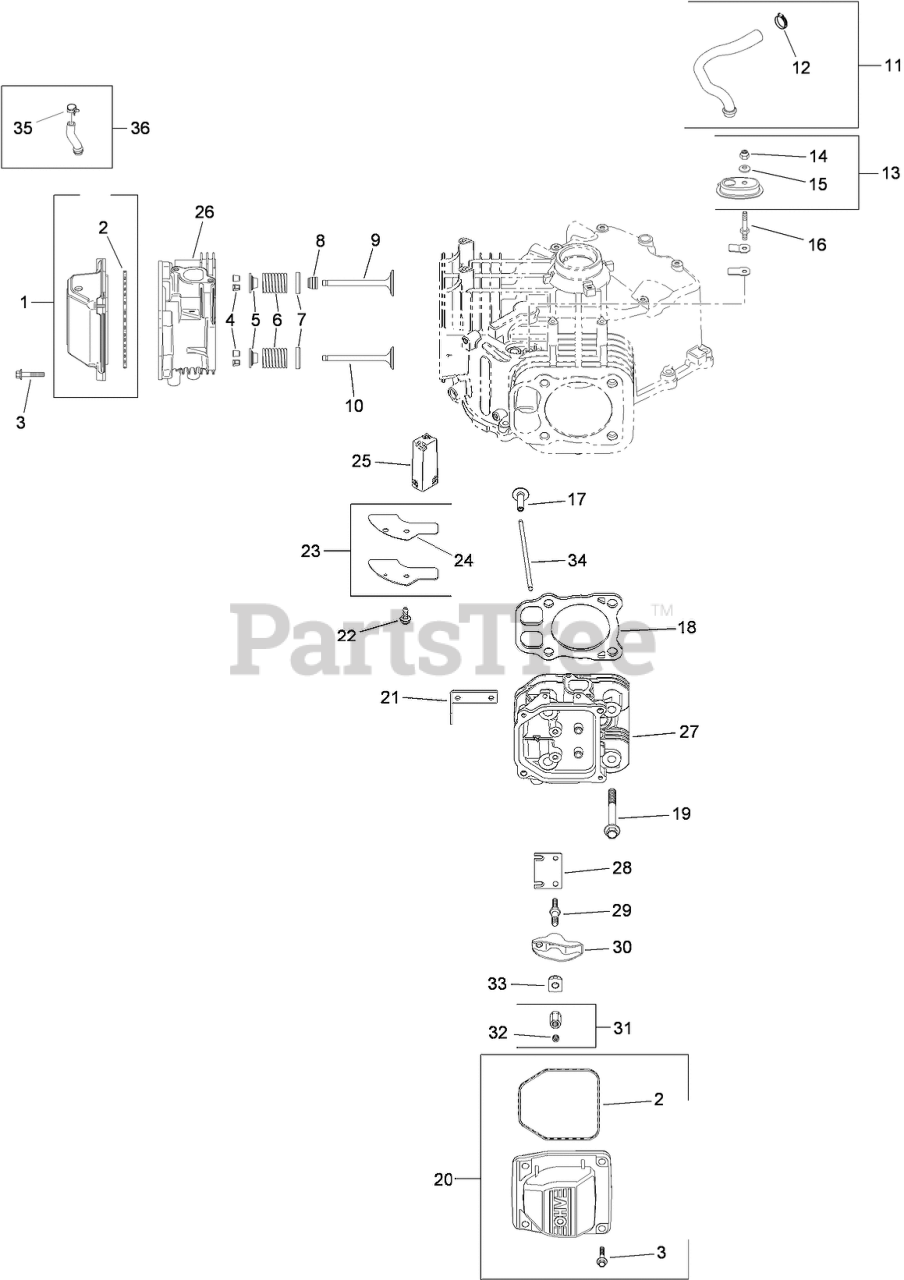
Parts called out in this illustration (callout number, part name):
1	BREATHER VALVE COVER KIT (INCLUDES REF 2)
2	O-RING
3	SCREW-FLANGE (M6X1.0X30)
4	RETAINER KIT
5	CAP-SPRING, VALVE
6	SPRING-VALVE
7	RETAINER-SPRING
8	SEAL-STEM, VALVE
9	VALVE-INTAKE (STD)
10	VALVE-EXHAUST (STD)
11	BREATHER HOSE KIT (INCLUDES REF 12)
12	CLAMP-HOSE, SPRING (1/2)
13	BREATHER HOUSING KIT (INCLUDES REF 14, 15)
14	NUT-LOCK (M5X.8)
15	WASHER-SEALING
16	STUD-COVER, BREATHER
17	TAPPET KIT
18	CYLINDER HEAD GASKET KIT
19	SCREW-FLANGE (M10X1.5X90)
20	PLAIN ROCKER COVER KIT (INCLUDES REF 2, 3)
21	STRAP-LIFTING
22	SCREW-FLANGE, THREAD FORMING (M6X1.0X16)
23	BREATHER COVER KIT (INCLUDES REF 24)
24	GASKET-COVER, BREATHER
25	FILTER-BREATHER
26	CYLINDER HEAD NO.1 ASM
27	CYLINDER HEAD NO.2 ASM
28	PLATE-GUIDE
29	STUD-ROCKER
30	ARM-ROCKER
31	HEX NUT ASM (INCLUDES REF 32)
32	SCREW-SET
33	PIVOT-ARM, ROCKER
34	ROD-PUSH
35	FUEL PUMP HOSE W/CLAMP KIT (INCLUDES REF 36)
36	CLAMP-HOSE
